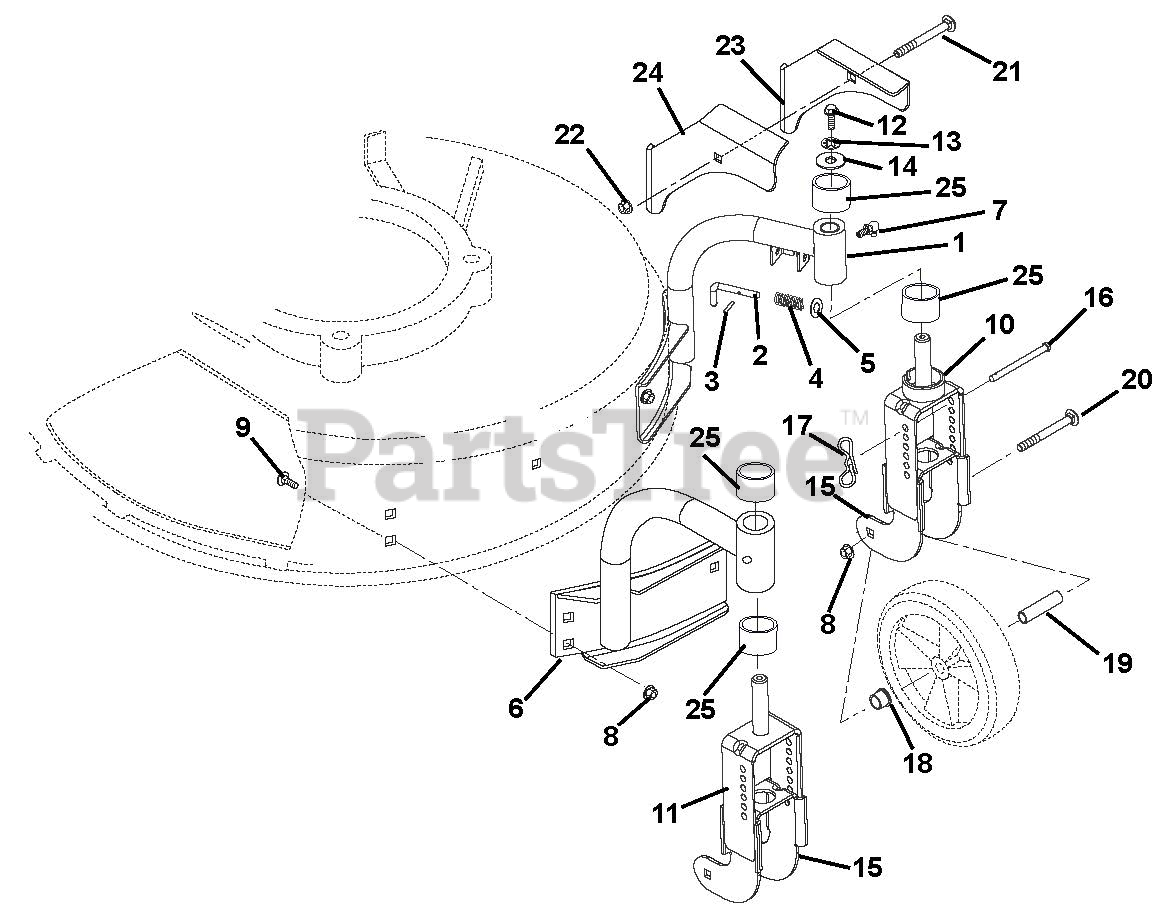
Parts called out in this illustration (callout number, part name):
1	WELDMENT, LH MOUNT
2	PIN, LOCKOUT
3	PIN-ROLL .093X.50
4	SPRG, COMP--SWVL LOCKOUT
5	@WSHR-FL-STL.281X.62X.065 YWZC
6	WELDMENT, RH MOUNT
7	FTG-LUBE .25-28X.256 YWZC
8	@NUT-LK-TOP-FLG .31-18 YWZC
9	@BLT-RDHDSQNK .31-18X.50 G5YZ
10	YOKE, OUTER LH
11	YOKE, RH OUTER
12	@BLT-HEX .25-20X.75 GR5 YWZC
13	WSHR-LK .250X.077 HVY YWZC
14	WSHR-FL-STL .281X1.000X.063
15	YOKE-INNER
16	PIN, HEIGHT ADJUSTMENT
17	PIN, BOW TIE LOCKING COTTER
18	BSHG-FLG .500X.625X.500X.750
19	SPCR, WHEEL .385X.500X2.00
20	BLT-RDHDSQSHNK.31-18X2.75G2YWZ
21	@BLT-RDHDSQNK .25-20X1.50 G5YZ
22	@NUT-SPNLK-FLG .25-20 YWZC
23	BRACKET, HOOD CABLE--LH
24	BRACKET, HOOD CABLE WELDMENT
25	BSHG-SLV .625X.750X.500 BR
26	@WSHR-FL-STL.250X.56X.049 YWZC
27	@PIN-CTR .09X.50 EXTPRSQCT YWZ
